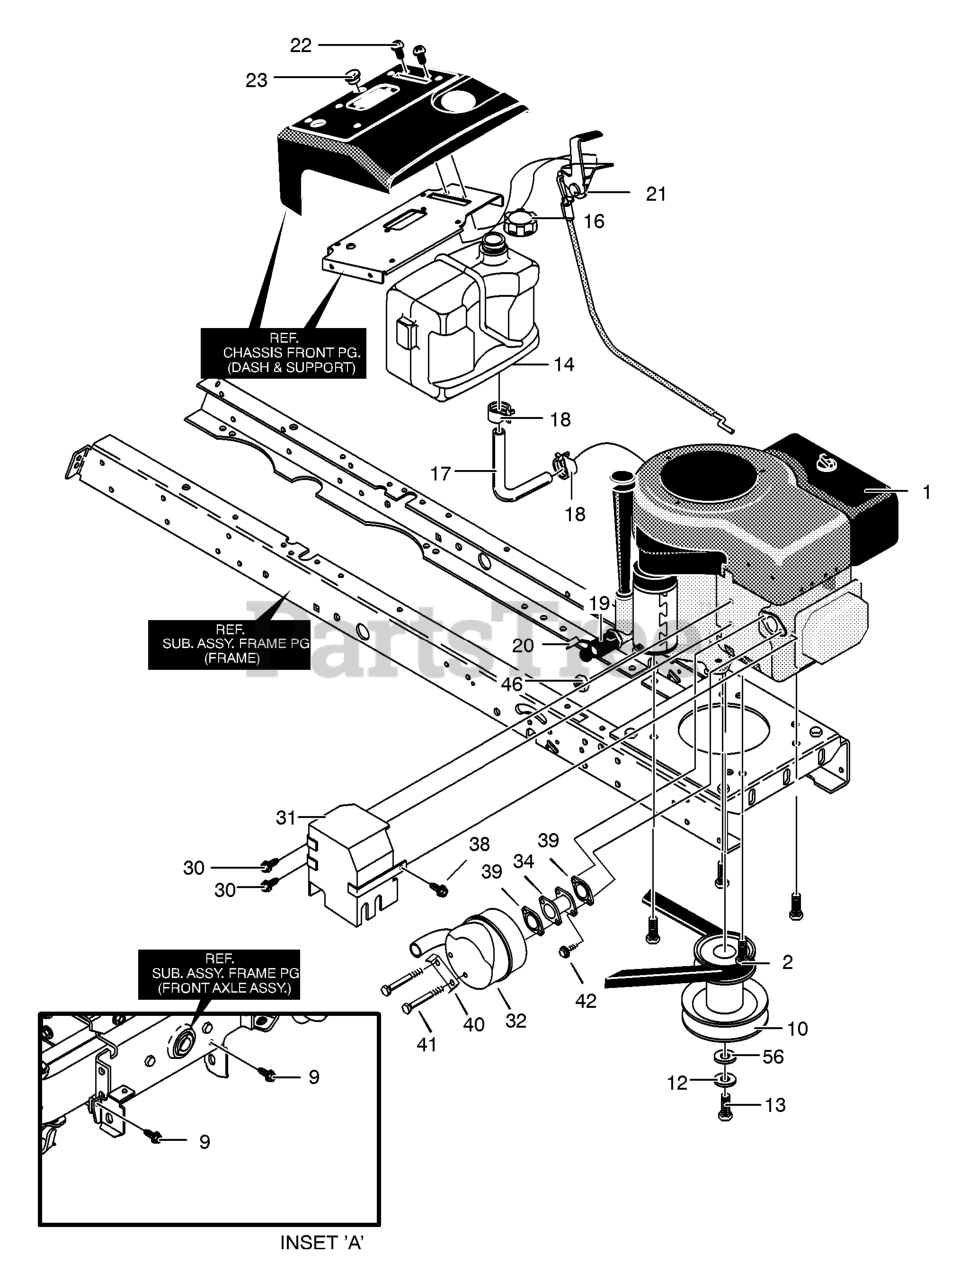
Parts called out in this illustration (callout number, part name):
1	ENGINE
2	BOLT 3/8 X 1.25
10	STACK PULLEY ASSEMBLY
14	TANK, FUEL-ASSEMBLY
16	FUEL CAP
17	Fuel Line (Must cut to length)
18	CLAMP, FUEL LINE
19	OIL DRAIN VALVE ASSEMBLY
20	CAP, OIL DRAIN VALVE
21	THROTTLE, CONTROL
23	PLUG, DASH
31	HEAT SHIELD ASSEMBLY
31-1	SHIELD, HEAT B/S
31-2	RIVET, POP
31-3	BRACKET, RIGHT
31-4	BRACKET, LEFT
31-5	PLATE, HEAT SHIELD
32	MUFFLER, ROUND
34	MUFFLER ADAPTER
39	GASKET, Exhaust
40	BRACKET, LOCK
46	NUT, 1/4--0
